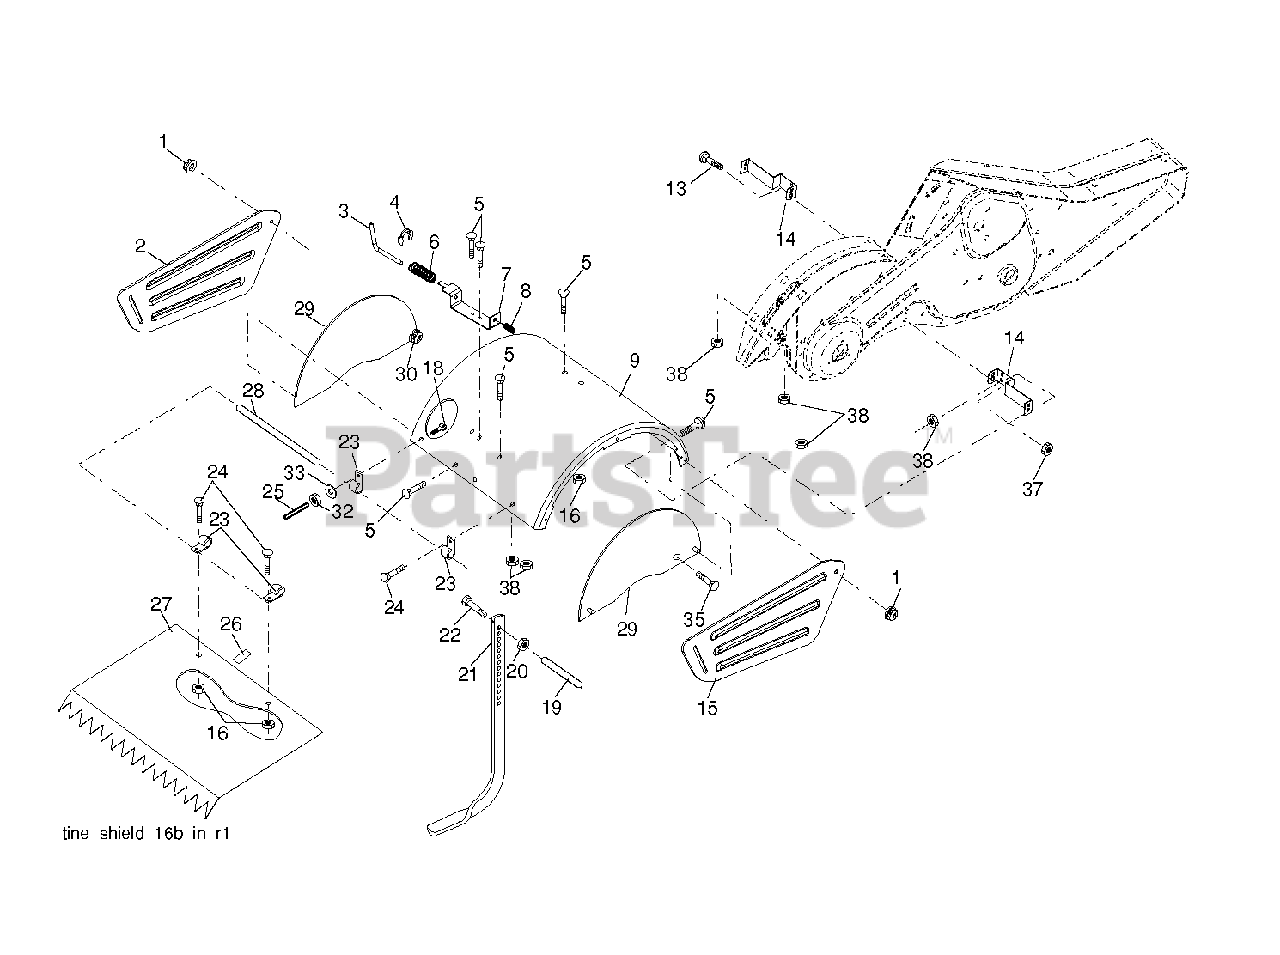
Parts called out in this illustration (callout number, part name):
1	NUT LOCK HEX FLANGE 5/16-18
3	STAKE PIN TI
4	RING, KLIP
5	BOLT, RDHD SQNK 5/16-18 X 3/4
6	SPRING TI
7	LATCH BRACKET TI
8	SPRING CRT
13	BOLT.CARRIAGE.5/16-18
14	BRACKET.TINE.SHIELD.TILLER
16	NUT T
20	NUT.HEX.3/8-16UNC
21	STAKE DEPTH CRT
22	BOLT.375-16
23	HINGE CRT
24	BOLT
25	VINYL CAP TI
26	PAD IDLER TI
28	PIN.HINGE.TILLER
30	LOCKNUT-FLANGE 5/16-18
32	NUT
33	LOCKWASHER
35	BOLT
37	NUT.71038.31-18.HEX.NYLOCK
38	NUT
